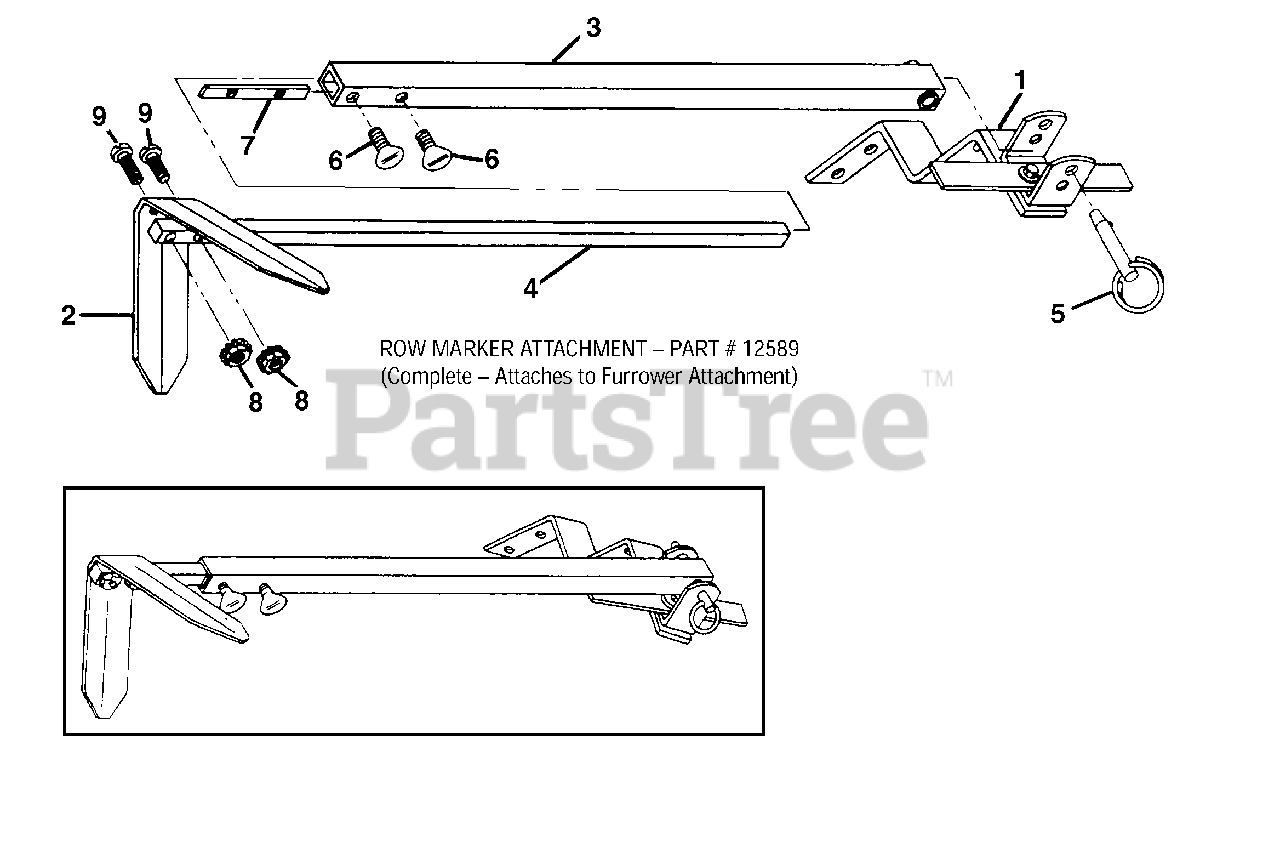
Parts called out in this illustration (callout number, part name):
1	Main Support & Yoke Assy-
2	Marker Blade-blade only
3	Marker Arm-main arm
4	Marker Arm-extension arm with stop pin
5	Hitch Pin-
6	Thumbscrew-1/4-20 x 1/2, not avail. sep.
7	Nut Bar-
8	Nut-hex, 10-24 w/attached start washers, not avail. sep.
9	Screw-round hd.,10-24 x 1, not avail. sep.
12589	Row Marker Attachment-
